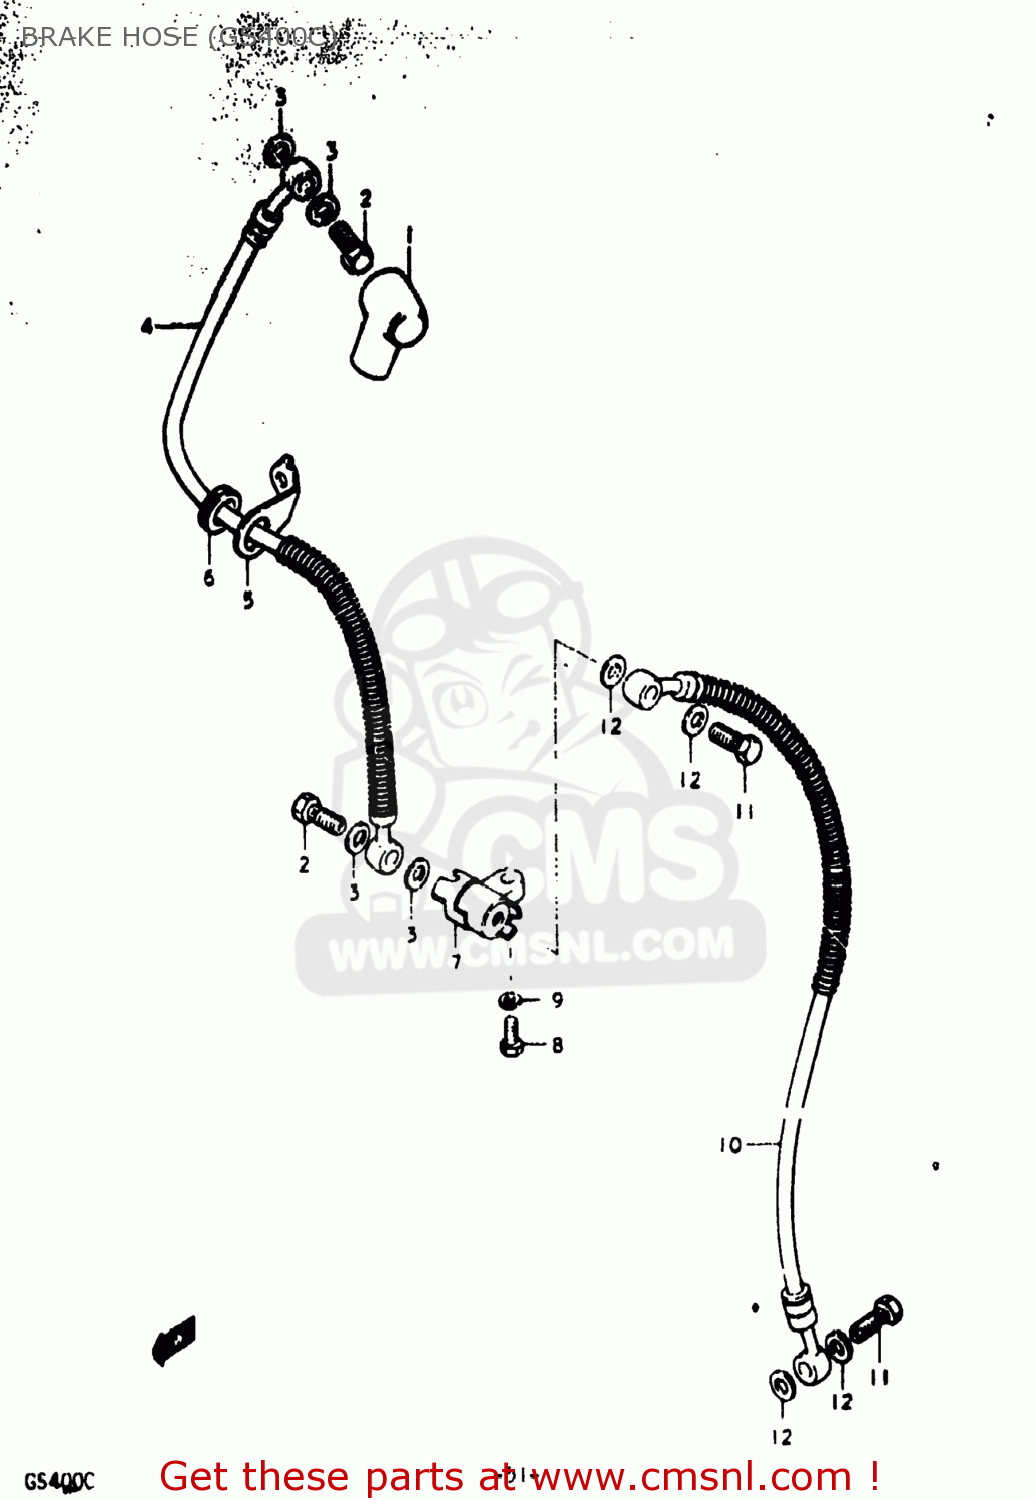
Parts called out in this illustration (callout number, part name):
1	BOOT,MASTER CYLINDER
2	BOLT UNION
3	WASHER
4	HOSE,FRONT BRAKE
5	GUIDE,BRAKE HOSE
6	GROMMET
7	JOINT,BRAKE HOSE
8	BOLT, UPPER
9	LOCK WASHER
10	HOSE,FRONT BRAKE
11	BOLT UNION
12	WASHER
